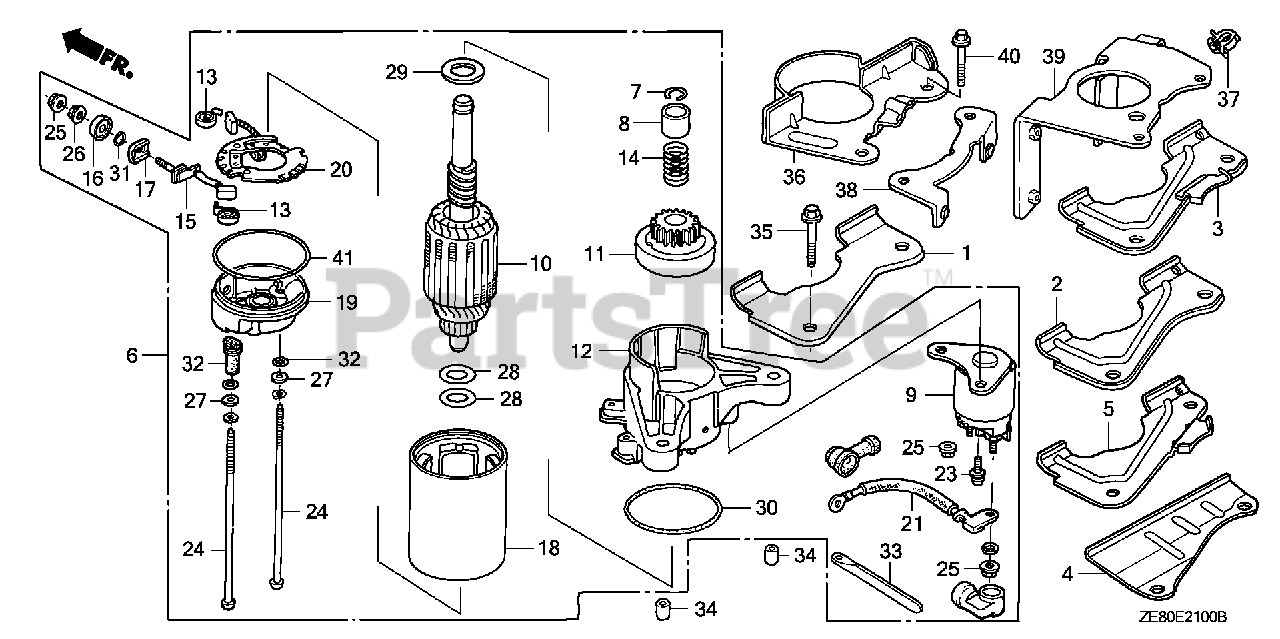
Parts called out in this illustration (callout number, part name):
36	PLATE, SIDE
39	STAY, STARTER
40	BOLT, FLANGE (8X28)
